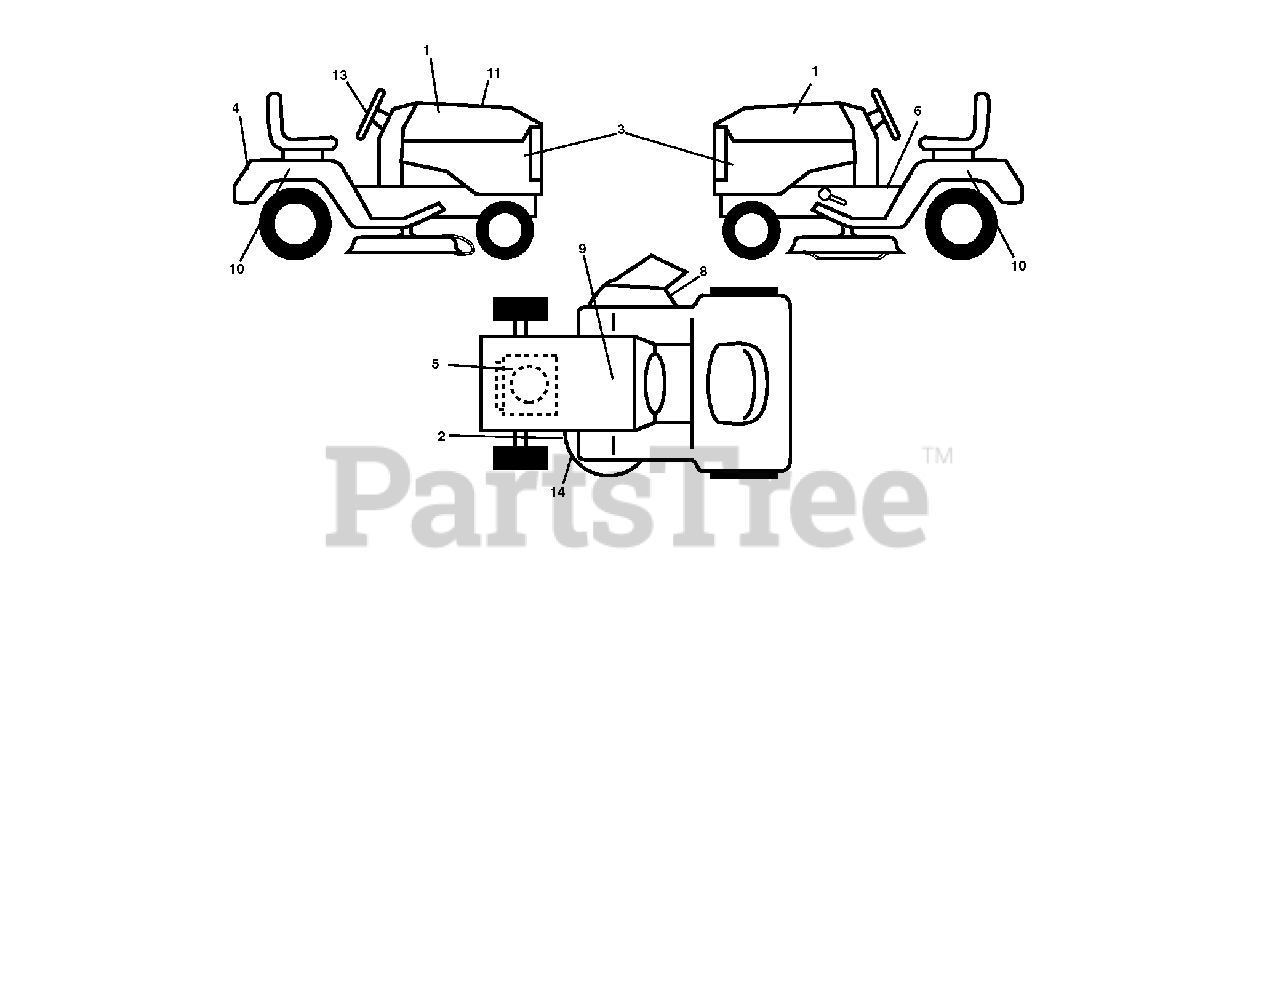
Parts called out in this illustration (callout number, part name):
2	DECAL.MOWER
5	DECAL.ENG.BS.26 HP.PROF.278955
6	Fender Warning Decal, English
8	DECAL.WARN.KEEP.HAND.AWAY
9	DECAL BTRY SYMBOLS
13	DECAL.STEER.WHEEL.POULAN.PRO
14	DECAL.MOWER.SCH.48/54
